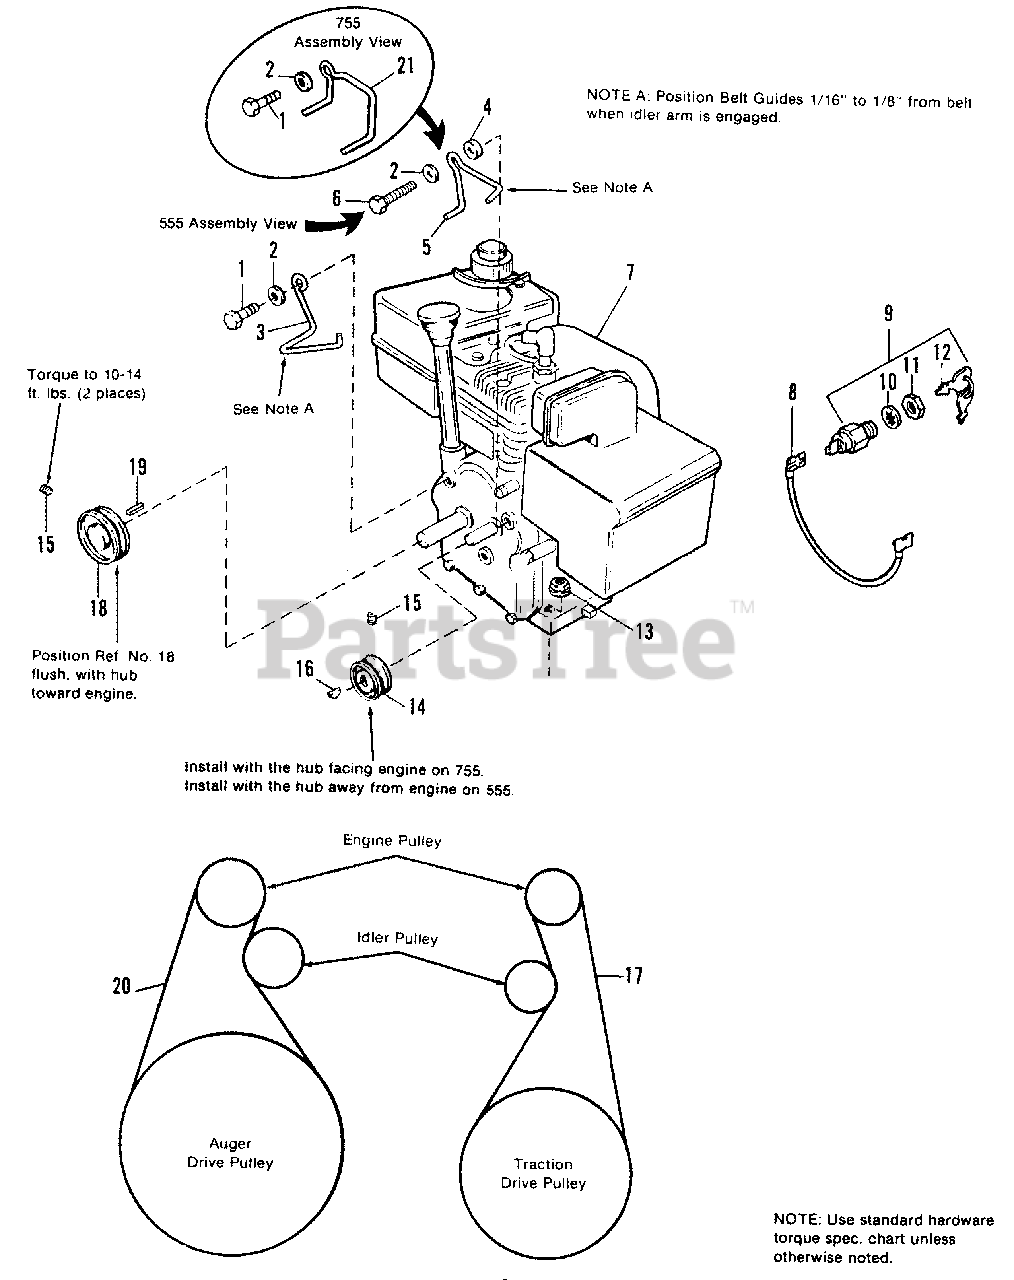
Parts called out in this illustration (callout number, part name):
1	CAPSCREW, Hex, 5/16-24 x 3/4 (Qty. 1, 5 HP)
2	WASHER, 5/16 (Qty. 3, 5 HP)
3	GUIDE, Belt
4	NUT, Hex Lock, 5/16-18 (5 HP Only)
5	GUIDE, Belt (5 HP Only)
6	STUD (5 HP Only)
7	ENGINE, 5 HP (Tecumseh)
7	ENGINE, 7 HP (Tecumseh)
7	ENGINE, 7 HP (Tecumseh) Manual Start
8	GROUND WIRE
9	SWITCH ASSY., Ignition w/Keys (Incl. Ref. Nos. 10, 11 & 12)
10	LOCKWASHER, 5/8
11	NUT, Hex, 5/8-32
12	KEY & RING ASSY.
13	NUT, Hex, Fl. Lock, 5/16-18
14	PULLEY, Idler (5HP Only)
14	PULLEY, Idler (7HP Only)
15	SETSCREW, Socket Hd., 5/16-18 x 5/16
16	KEY, Woodruff, 1/8 x 5/8
17	BELT, Traction Drive (5HP Only)
17	BELT, Traction Drive (7HP Only)
18	PULLEY, Engine
19	KEY, Sq., 3/16 x 3/16 x 1
20	BELT, Auger Drive
21	GUIDE, Belt (7 HP Only)
